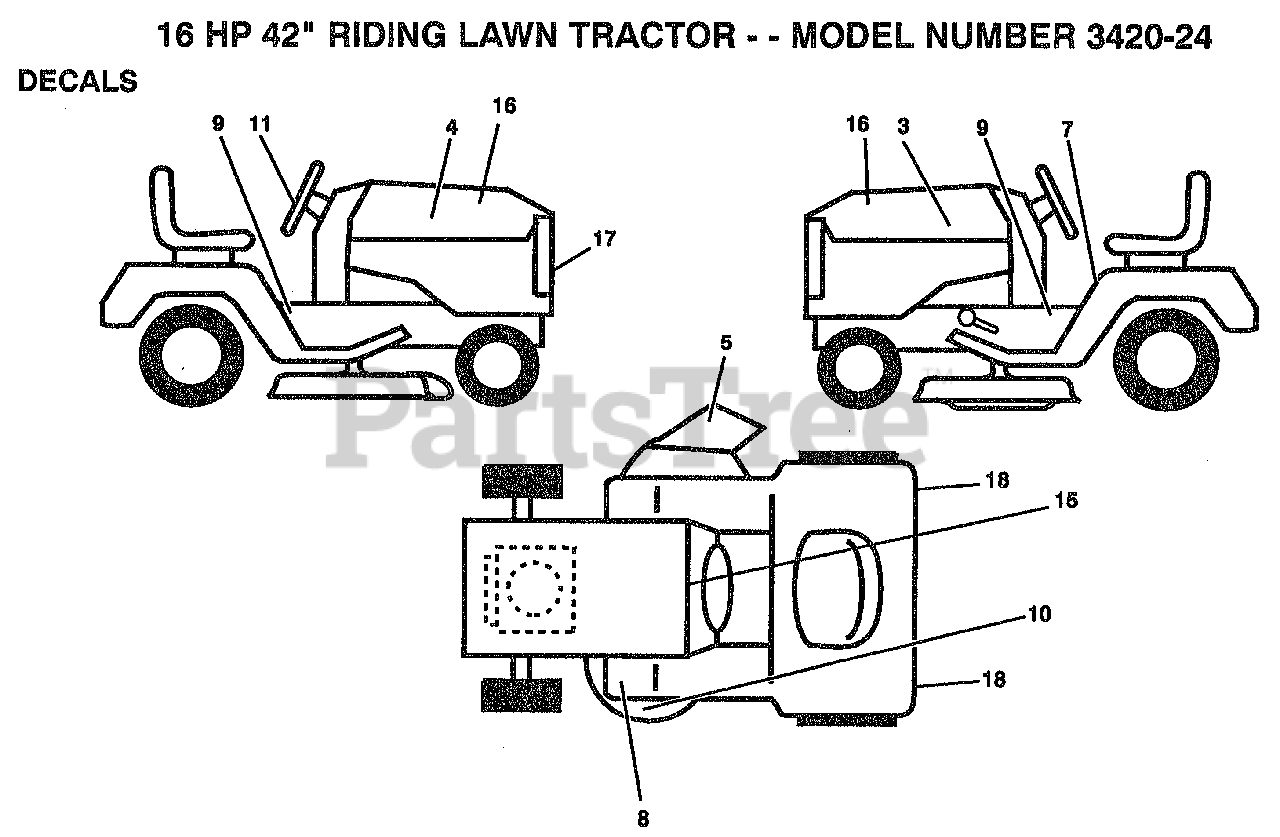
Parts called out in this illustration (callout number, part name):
3	HOOD DECAL LH
5	DECAL WARNING
7	DECAL CAUTION
8	DECAL T
9	DECAL CHASSIS
10	DECAL YT
11	DECAL STEERING WHEEL INSERT
16	NAMEPLATE LOGO
17	GRILL DECAL
18	REFLECTOR-TAIL YT
